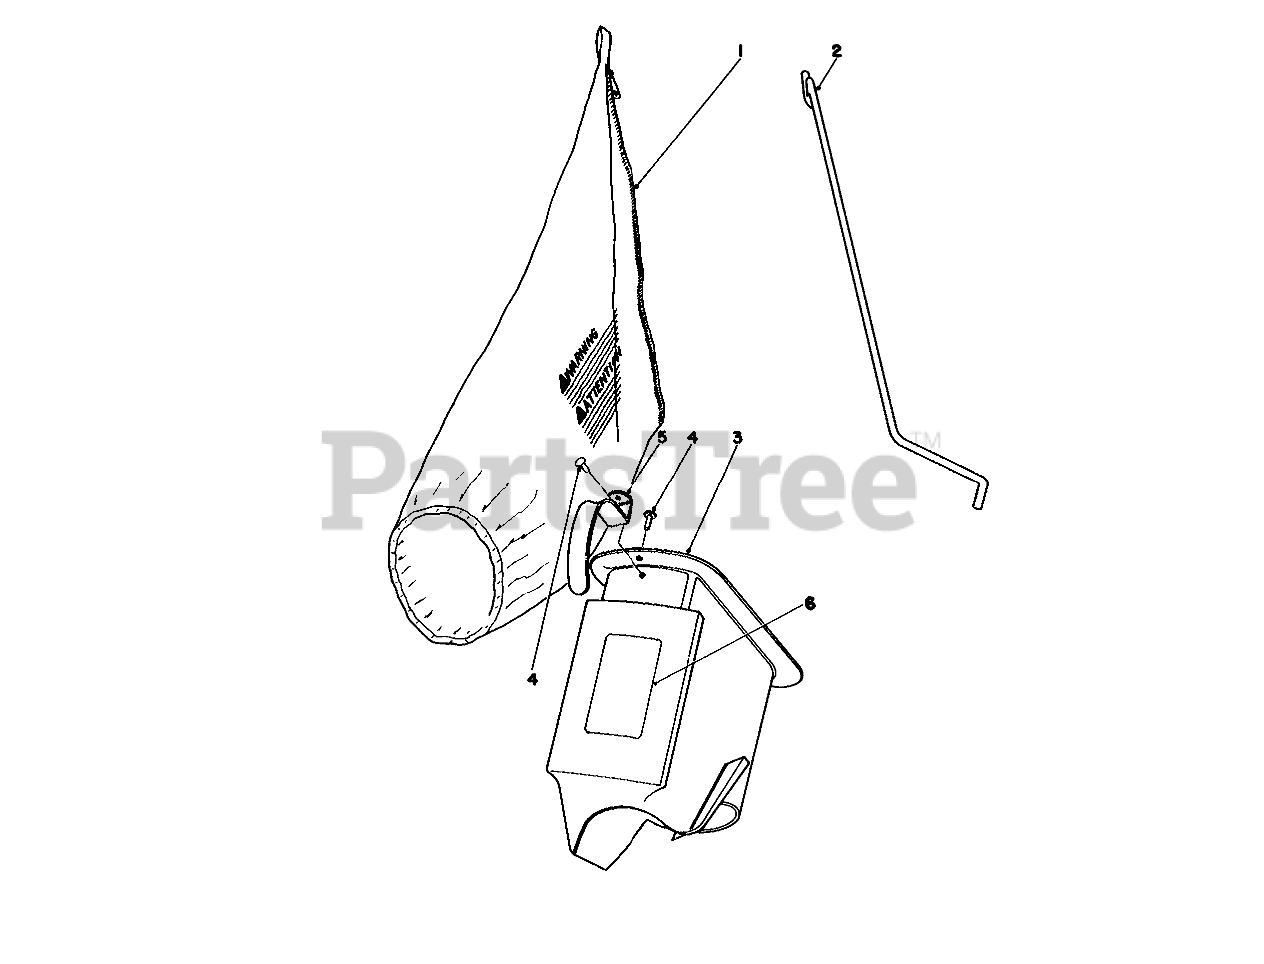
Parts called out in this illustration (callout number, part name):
1	BAG REPLACMNT44-0540
2	Bag Rod
3	Grass Chute (Incl. Ref. #4 & 5)
4	RIVET 3/16 X 7/16
5	HANDLE-GRASS CHUTE
6	BAG CHUTE DECAL
